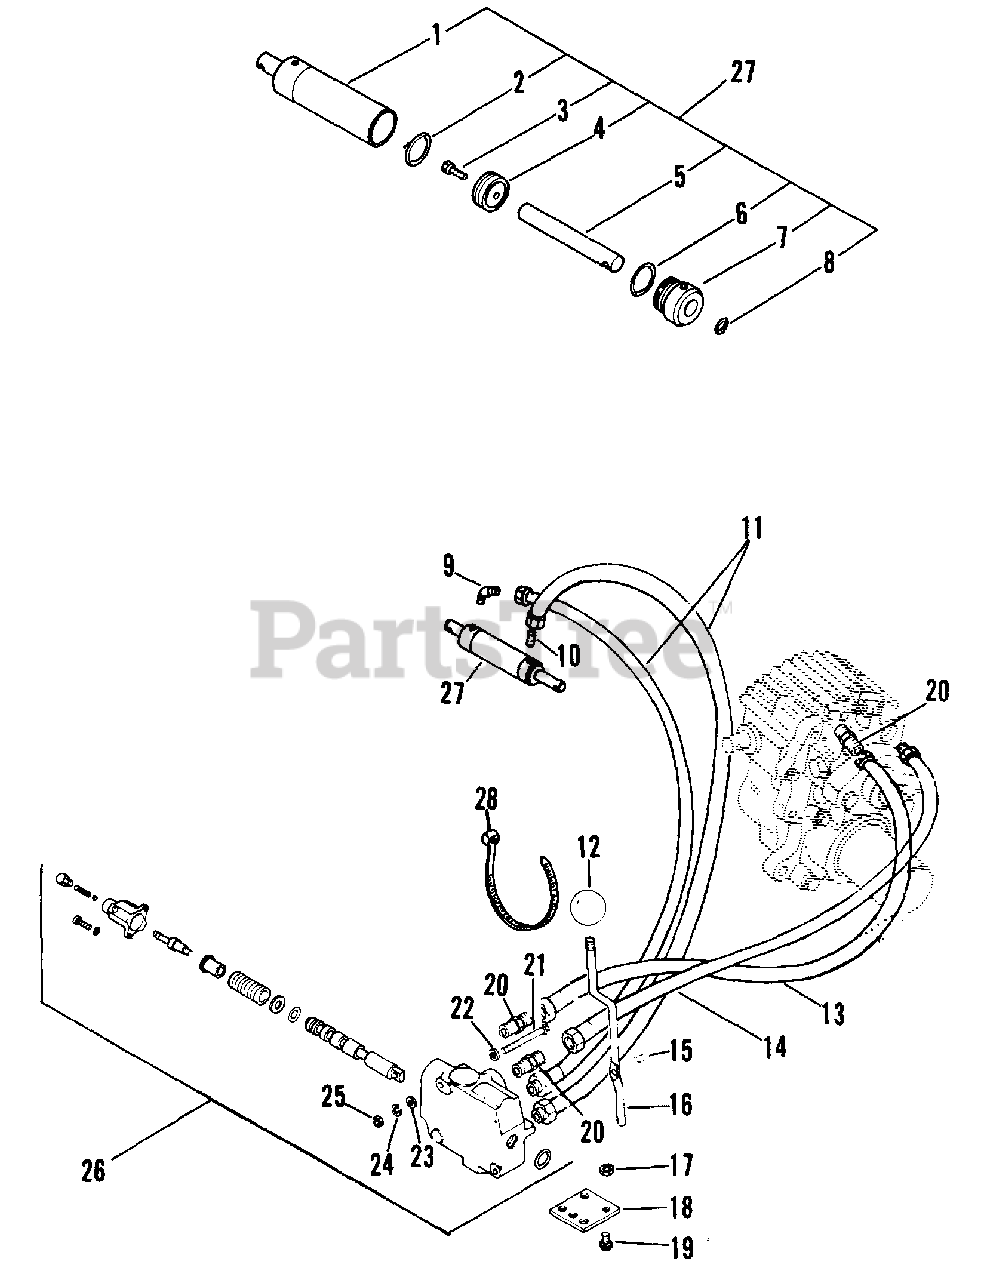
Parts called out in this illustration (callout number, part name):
1	Cylinder
2	O-Ring, 1-5/8 Nom. I.D.
3	Screw, Cap 3/8-24 x 1.00 S.H.
4	Piston
5	Rod
6	O-Ring, 2-1/8 Nom. I.D.
7	Rod Cap
8	O-Ring, 1 Nom. I.D.
9	Adapter 9/16 to 1/4
10	Adapter
11	Hydraulic Hose
12	Knob, Steering Lock
13	Hydraulic Hose
14	Hydraulic Hose
15	Pin, Groove 1/4 x 3/4 Type B
16	Control Rod
17	Nut, Lock 5/16-18
18	Pivot Bracket
19	Bolt, 5/16-18 x .625 Rd Hd Sq Nk
20	Connector
21	Bolt, Hex 1/4-20 x 2.25
22	Washer, Flat .281 x .625 x .065
23	Washer, .245/.265 x .562 x .125
24	Washer, Lock 1/4 Reg.
25	Nut, Hex 1/4-20
26	Hydraulic Control Valve
27	Cylinder Assembly
28	Tie, Cable
